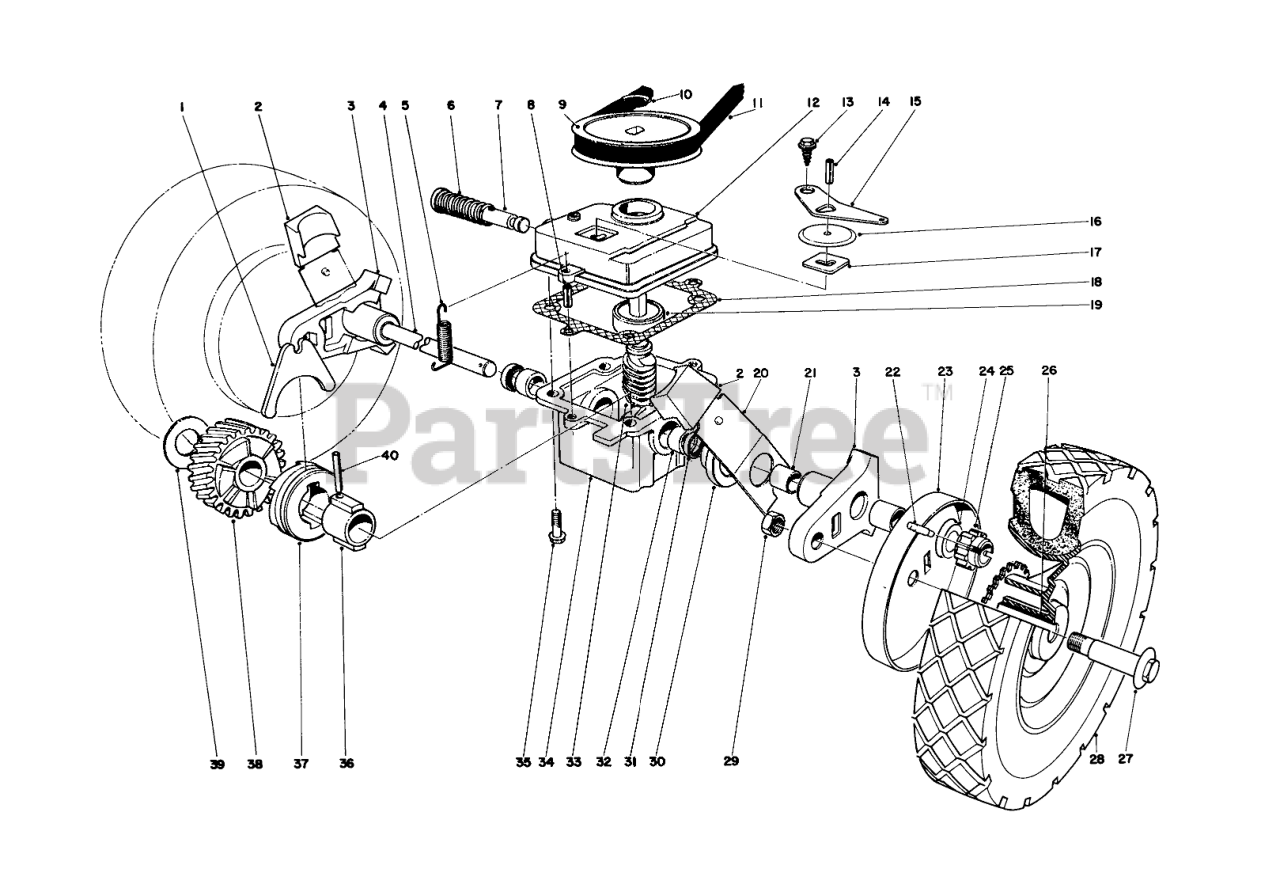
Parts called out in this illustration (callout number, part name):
1	SHIFTER FORK
2	Knob
3	Pivot Arm (Incl. Ref. #21)
4	Drive Shaft
5	TENSION SPRING
6	SPRING
7	Shift Rod
8	3/16 X 1/2 ROLL PIN
9	PULLEY
10	PUSH-ON 93-3236
11	V BELT
12	GEAR CASE COVER
13	Screw
14	PIN-ROLL
15	SHIFTER ARM
16	TRANS DUST COVER
17	LATCH PLATE
18	GASKET
19	Bearing
20	LH SPRING ARM ASM
21	BUSHING
22	PIN-GROOVED
23	WHEEL COVER
24	WASHER-THRUST
25	Pinion
26	WHEEL BUSHING
28	Tire 8" w/Wheel (Incl. Ref. #26)
29	Nut
30	End Cap
31	Seal
32	Bushing
33	WORM SHAFT
34	Gear Case (Incl. Ref. #31 & 32)
35	Screw
36	SLEEVE
37	CLUTCH JAW
39	THRUST WASHER
40	COIL PIN
